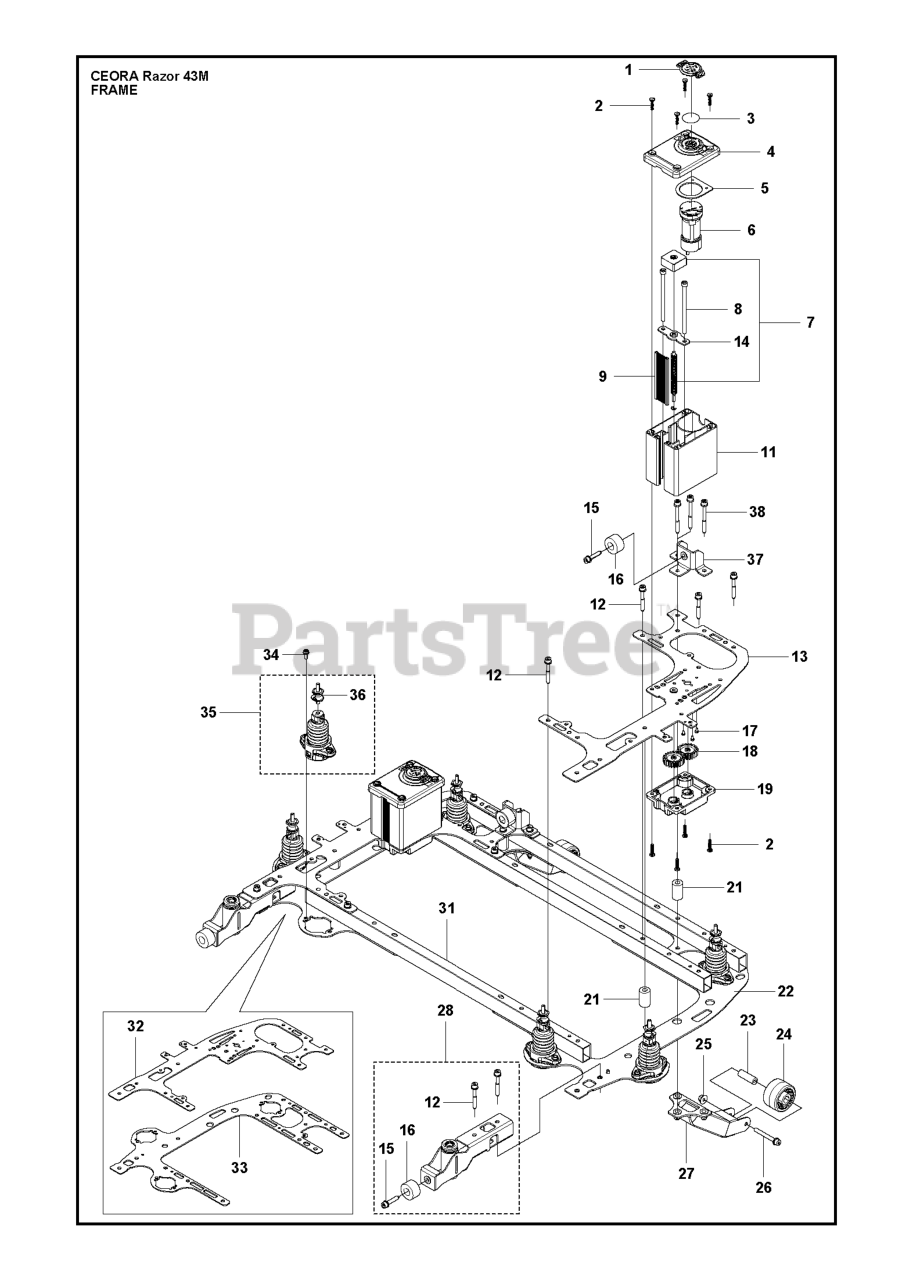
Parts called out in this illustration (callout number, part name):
1	COVER
2	SCREW
3	KIT AIR FILTER KIT 305 - 10 PC
4	COVER HEIGHT ADJUSTMENT UPPER
5	GASKET HEIGHT ADJUSTMENT HOUSI
6	MOTOR HEIGHT ADJUSTMENT
7	WORM GEAR ASSY WORM GEAR LIN
8	SCREW IHSCM.
9	BRUSH 15X5X95
11	HOUSING HEIGHT ADJUSTMENT MOTO
12	SCREW ISO 10644 M6X45-10.9-S1
13	PLATER UPPER LEFT
14	BRACKET HEIGHT ADJUSTMENT LIMI
15	SCREW ISO 10644 M6X30-10.9-S1
16	DAMPER RUBBER D30 H17
17	SCREW
18	GEAR HEIGHT ADJUSTMENT M1.5 N2
19	COVER HEIGHT ADJUSTMENT LOWER
21	SLEEVE
22	PLATE LOWER LEFT
23	SLEEVE SUPPORT WHEEL
24	WHEEL SUPPORT WHEEL
25	NUT FLANGE
26	BOLT
27	SUPPORT SUPPORT WHEEL SUSPENSI
28	HOLDER KIT WHEEL A120
31	BEAM ALU-PROFILE - 30X20X2 CD
32	PLATE UPPER RIGHT
33	PLATE LOWER RIGHT
34	SCREW
35	JOYSTICK ASSY FOR RUBBER DAMPE
36	DAMPER RUBBER A19.5 H19 M6X11.
37	SUPPORT COLLISION LIMITER
38	SCREW ISO 10644 M6X60-10.9-S1
